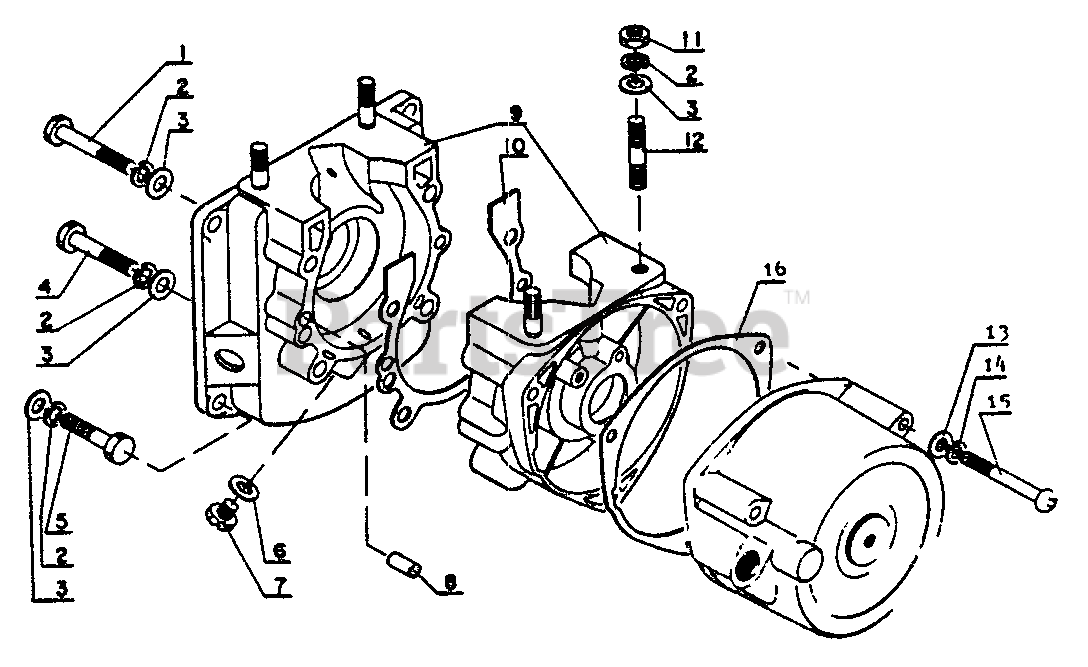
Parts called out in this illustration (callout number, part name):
1	BOLT
2	LOCKWASHER - 6
3	WASHER - 6
4	BOLT
5	BOLT - 6X25
7	BOLT, DRAIN
8	PIN - LOCATING
9	CRANKCASE KIT
10	GASKET, CRANKCASE
11	LOCKNUT - 6
13	WASHER - 5
14	LOCKWASHER - 5
15	SCREW - 5X40
16	GASKET, STARTER
